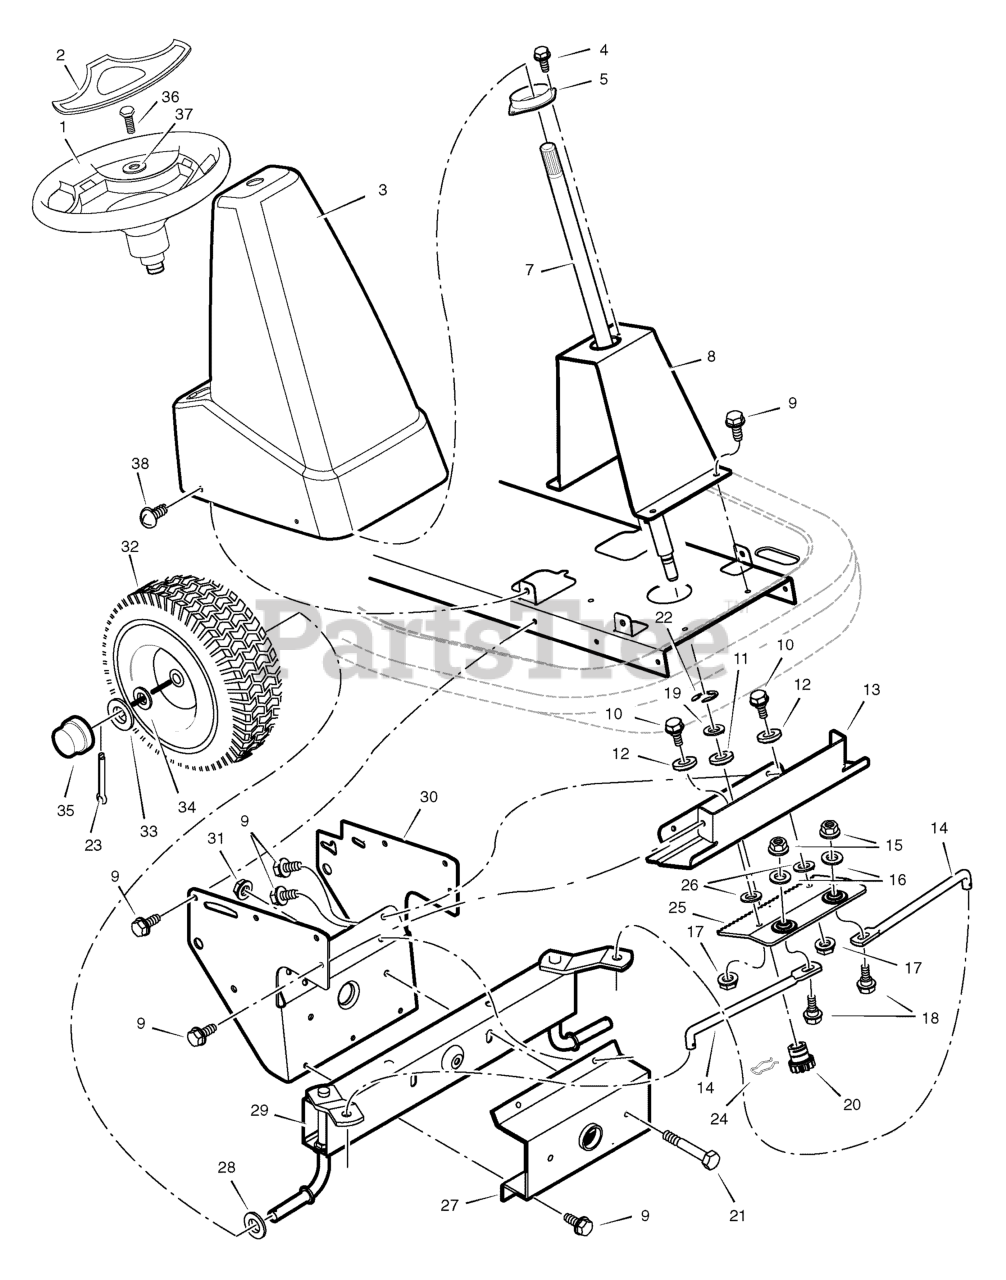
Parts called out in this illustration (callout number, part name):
1	WHEEL, Steering
2	CAP, Steering
3	Console, High -Black
5	BEARING, Upper Steering
7	SHAFT, Steering
8	SUPPORT, Steering
10	BOLT, Shoulder
11	BEARING, Lower Steering
13	PLATE, Gear Mounting
15	NUT, Flange
17	NUT, Flange
18	BOLT, Hex
19	WASHER, 1-1.3 16G FLT
20	GEAR, Pinion
21	BOLT, Hex
22	E-RING, Retainer
23	PIN, Cotter
24	RETAINER, Spring
25	RACK, Steering
27	BRACKET, Axle Front
29	AXLE & SPINDLE ASSEMBLY
30	BRACKET, Support
31	NUT, Flange
32	WHEEL, Front
